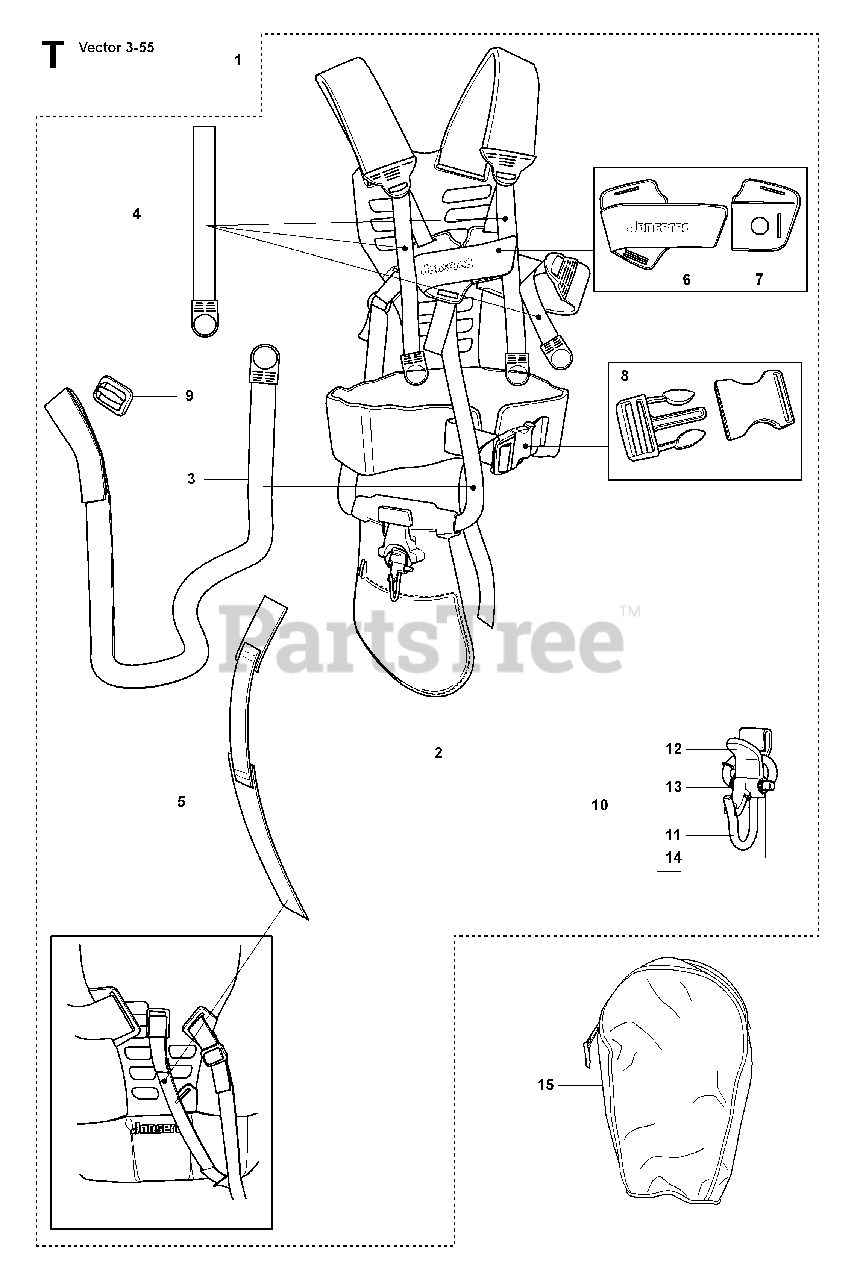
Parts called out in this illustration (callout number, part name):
6	FRONT PIECE
7	FRONT PIECE
9	CLIP
10	WELT HOOK
